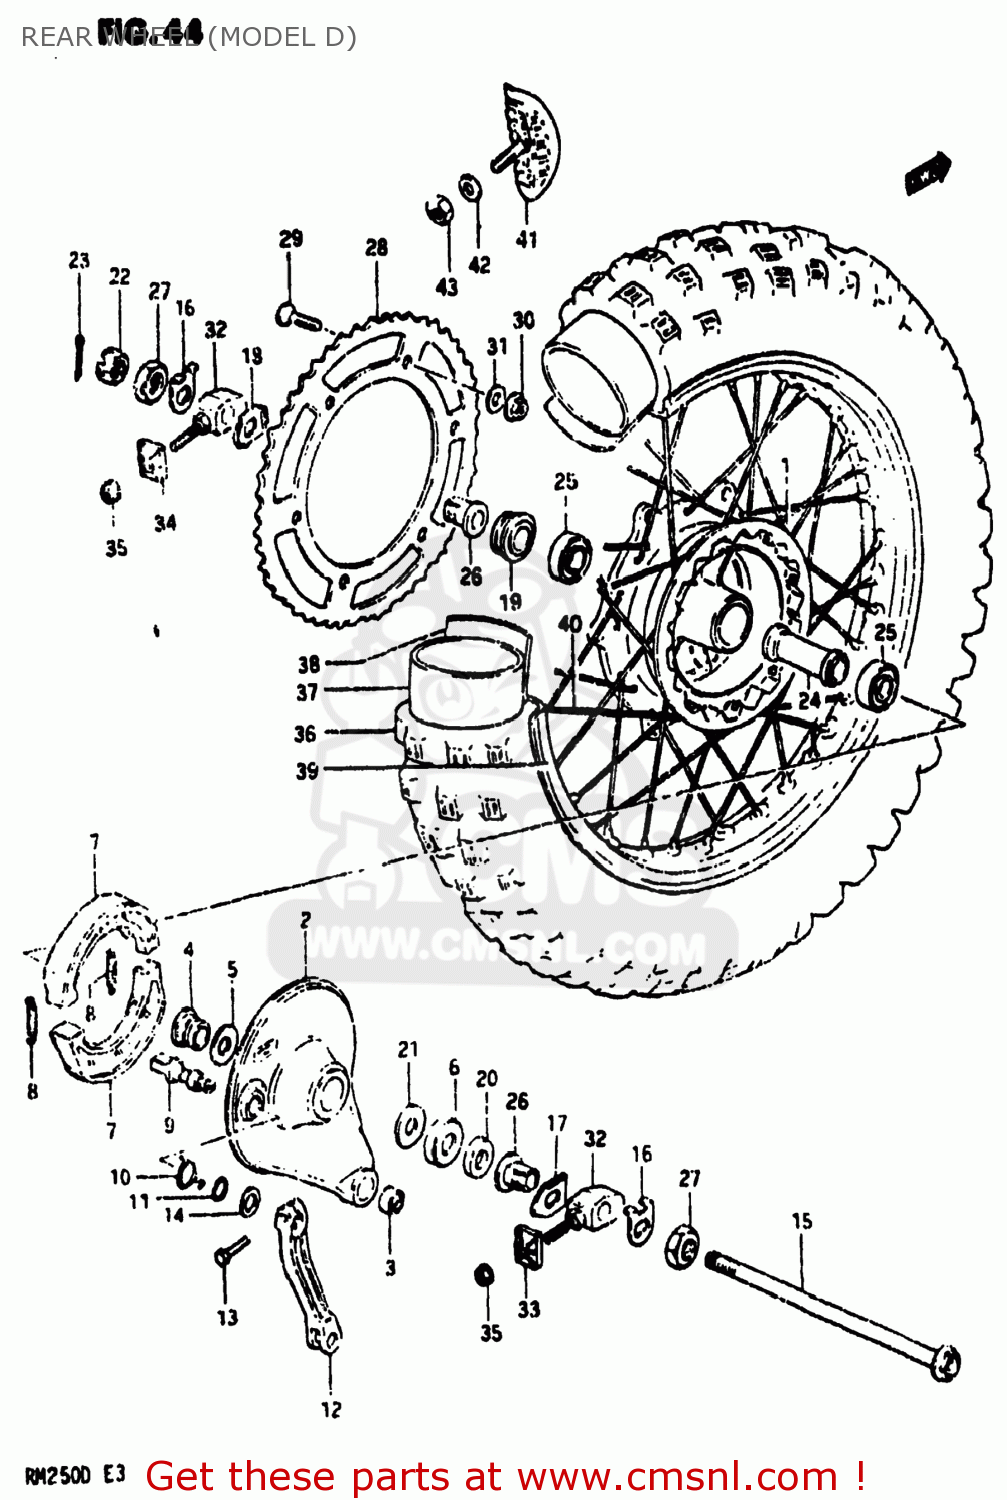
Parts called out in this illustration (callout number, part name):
1	DRUM,REAR HUB
2	PANEL SET,REAR HUB
3	SPHERICAL BRNG,TORQUE LINK
4	SPACER,RR BRAKE ANCHOR PANEL
5	SEAL,OIL(20X27X5)
6	CVR,RR BRAKE AHR PNL DUST SEAL
7	SHOE,BRAKE (MCA)
8	SPRING(L:34)
9	CAM,FR BRAKE
10	SPRING
11	O RING(D:2.5,ID:11.4)
12	LEVER,RR BRAKE CAM
13	BOLT
14	WASHER(12.5X20X1)
15	AXLE,REAR
16	WASHER,CHAIN ADJUSTER GUIDE
17	PLATE,CHAIN ADJUSTER,RIGHT
18	PLATE,CHAIN ADJUSTER,LEFT
19	SPACER,RR AXLE,L
20	SPACER,REAR AXLE,RIGHT
21	WASHER,THRUST
22	NUT
23	COTTER PIN
24	SPACER
25	BEARING
26	SPACER,CHAIN ADJUSTER
27	NUT
28	SPROCKET,REAR
29	SCREW(8X33.5)
30	NUT
31	WASHER
32	ADJUSTER,CHAIN
33	PLATE,CHAIN ADJUSTER GEAR
34	PLATE,CHAIN ADJUSTER GEAR
35	NUT
36	TIRE
37	TUBE,INNER
38	PROTECTOR,WHEEL,INNER
39	RIM,REAR WHEEL
40	SPOKE SET,REAR WHEEL
41	STOPPER,BEAD
42	WASHER
43	NUT
